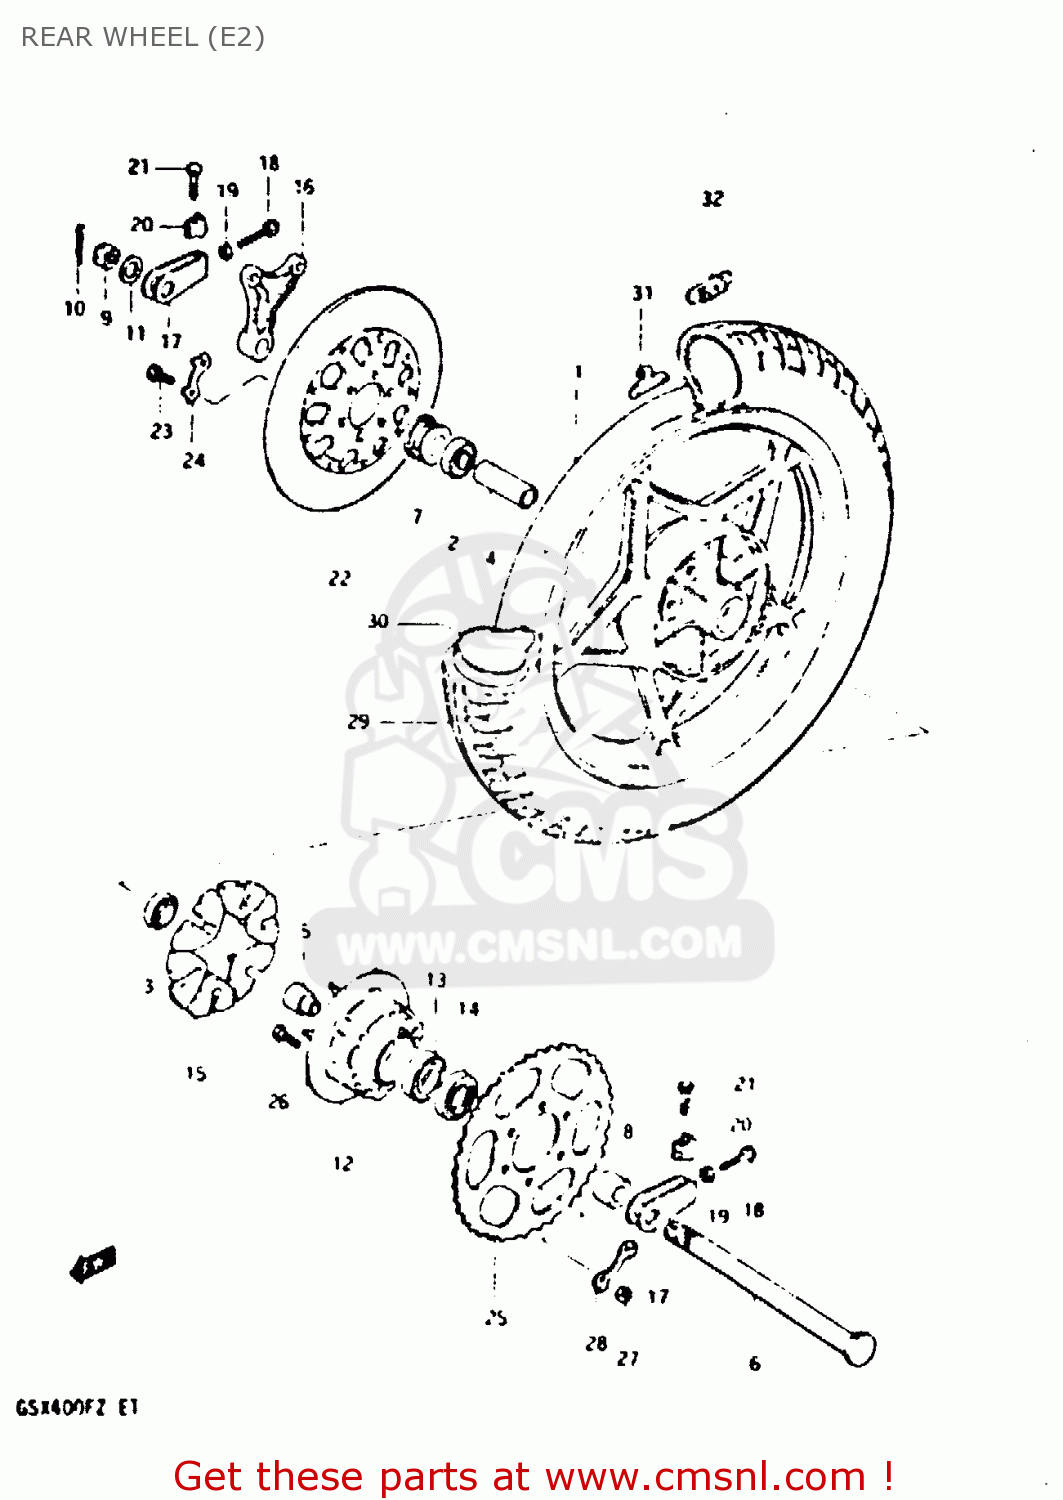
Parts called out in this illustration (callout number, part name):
1	WHEEL, REAR (18*MT*2.15)
2	BEARING
3	BEARING
4	SPACER, BEARING
5	SPACER,REAR HUB BEARING
6	AXLE, REAR
7	SPACER,REAR AXLE
8	SPACER(17X30.5X16.3)
9	NUT
10	PIN,COTTER
11	WASHER (17X30X3.2)
12	DRUM,REAR SPROCKET MOUNT
13	BEARING
14	SEAL,OIL(30.5X52X8)
15	ABSORBER,RR HUB SHOCK
16	BRACKET, REAR CALIPERS
17	ADJUSTER,CHAIN
18	BOLT
19	NUT
20	SUPPORTER,CHAIN ADJUST
21	BOLT
22	DISC, REAR BRAKE
23	BOLT(8X25)
24	WASHER
25	SPROCKET,REAR
26	BOLT
27	NUT
28	WASHER
29	TIRE (3.75S-18)
30	TUBE,INNER
31	BALANCER,WHEEL
32	BALANCER,WHEEL
